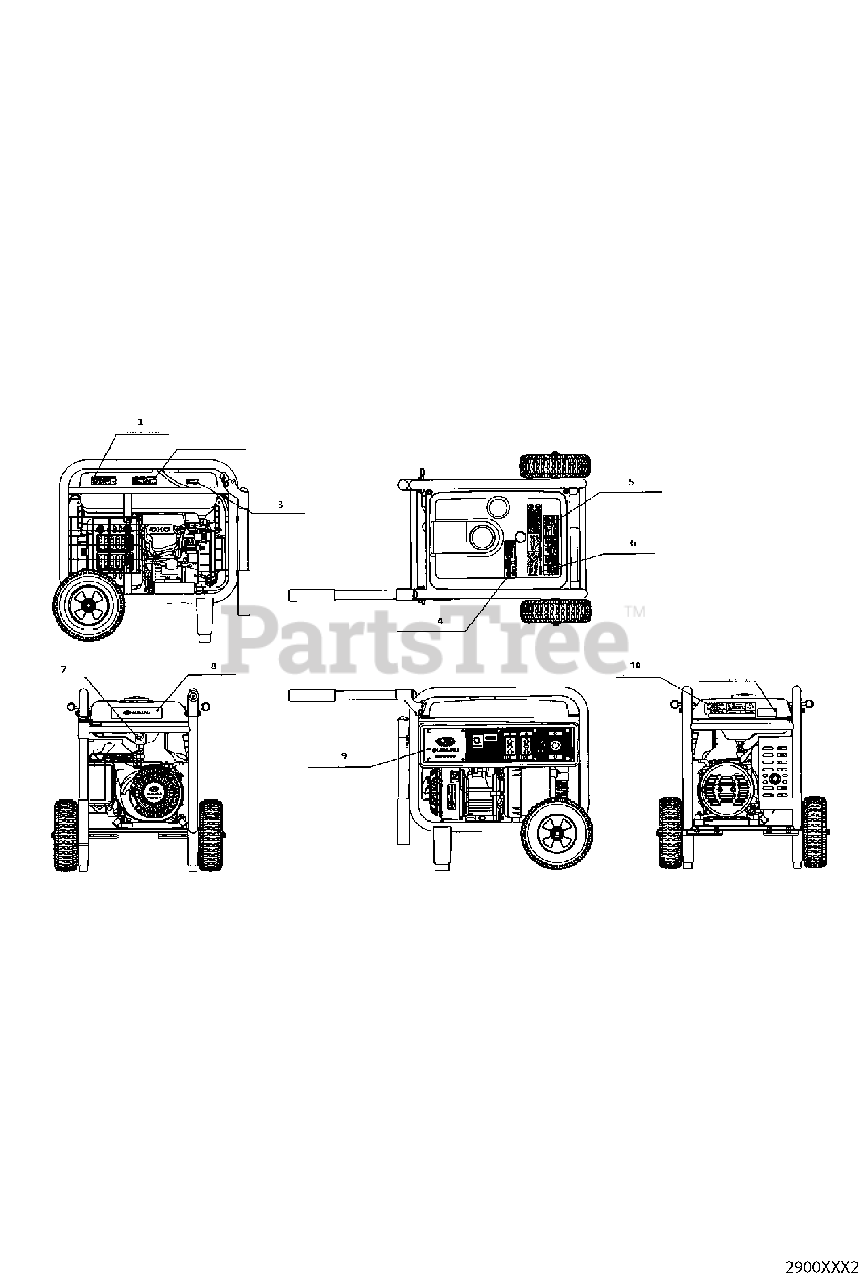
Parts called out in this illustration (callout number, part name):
4	LABEL,OIL LEVEL WARNING
7	LABEL(FUEL COCK)
8	LABEL,TRADE MARK
9	LABEL,TRADE MARK
